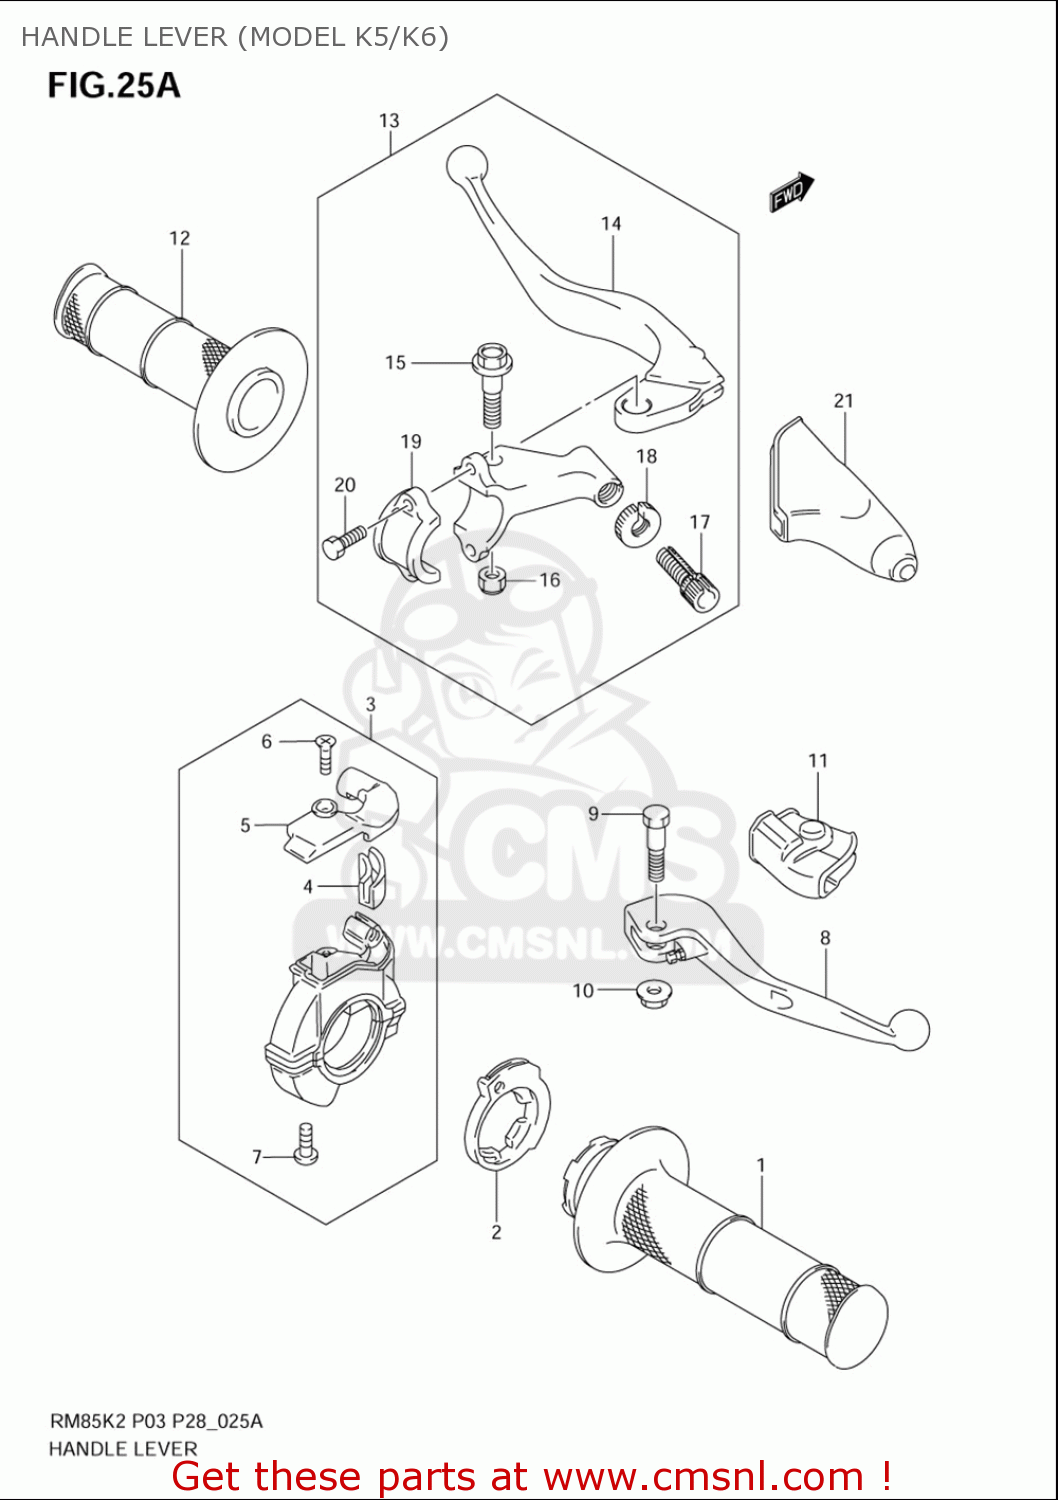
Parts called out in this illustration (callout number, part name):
1	GRIP,THROTTLE
2	ROTOR,THROTTLE GRIP
3	CASE ASSY,THROTTLE
4	GUIDE PIECE,THROTTLE
5	COVER,THROTTLE CASE
6	SCREW
7	SCREW
8	LEVER ASSY,BRAKE
9	BOLT,BRAKE LEVER
10	NUT
11	COVER,BRAKE LEVER
12	GRIP,L
13	LEVER ASSY,CLUTCH
14	LEVER,CLUTCH
15	BOLT,LEVER
16	NUT 6MM
17	ADJUSTER,WIRE
18	NUT,LOCK
19	BRACKET,CLUTCH LEVER HOLDER
20	BOLT
21	COVER,CLUTCH LEVER
